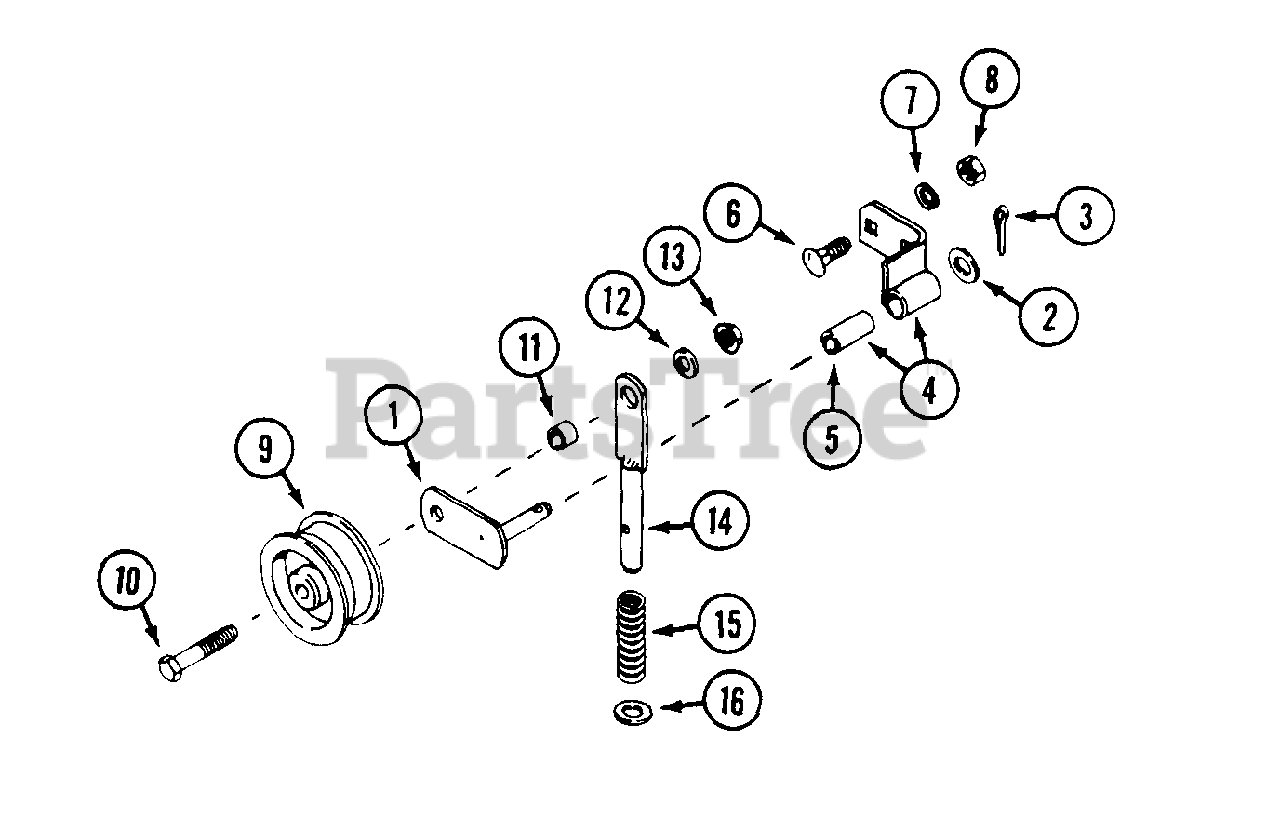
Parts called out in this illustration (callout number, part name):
1	ARM - idler
2	WASHER - 1/2" x 7/8"
3	PIN - cotter 3/32" x 3/4"
4	BRACKET - pivot
5	BUSHING - .50" x .62" x 1.5"
6	BOLT - carriage 3/8" - 16 x 1"
7	LOCKWASHER - 3/8"
8	NUT - 3/8" - 16
9	PULLEY - 3.25" x 1.38"
10	BOLT - 3/8" - 16 x 2-1/4"
11	SPACER - .38" x .62" x .41"
12	WASHER - 3/8"
13	NUT - 3/8" - 16 flange lock
14	GUIDE - spring
15	SPRING - compression
16	WASHER - thrust
